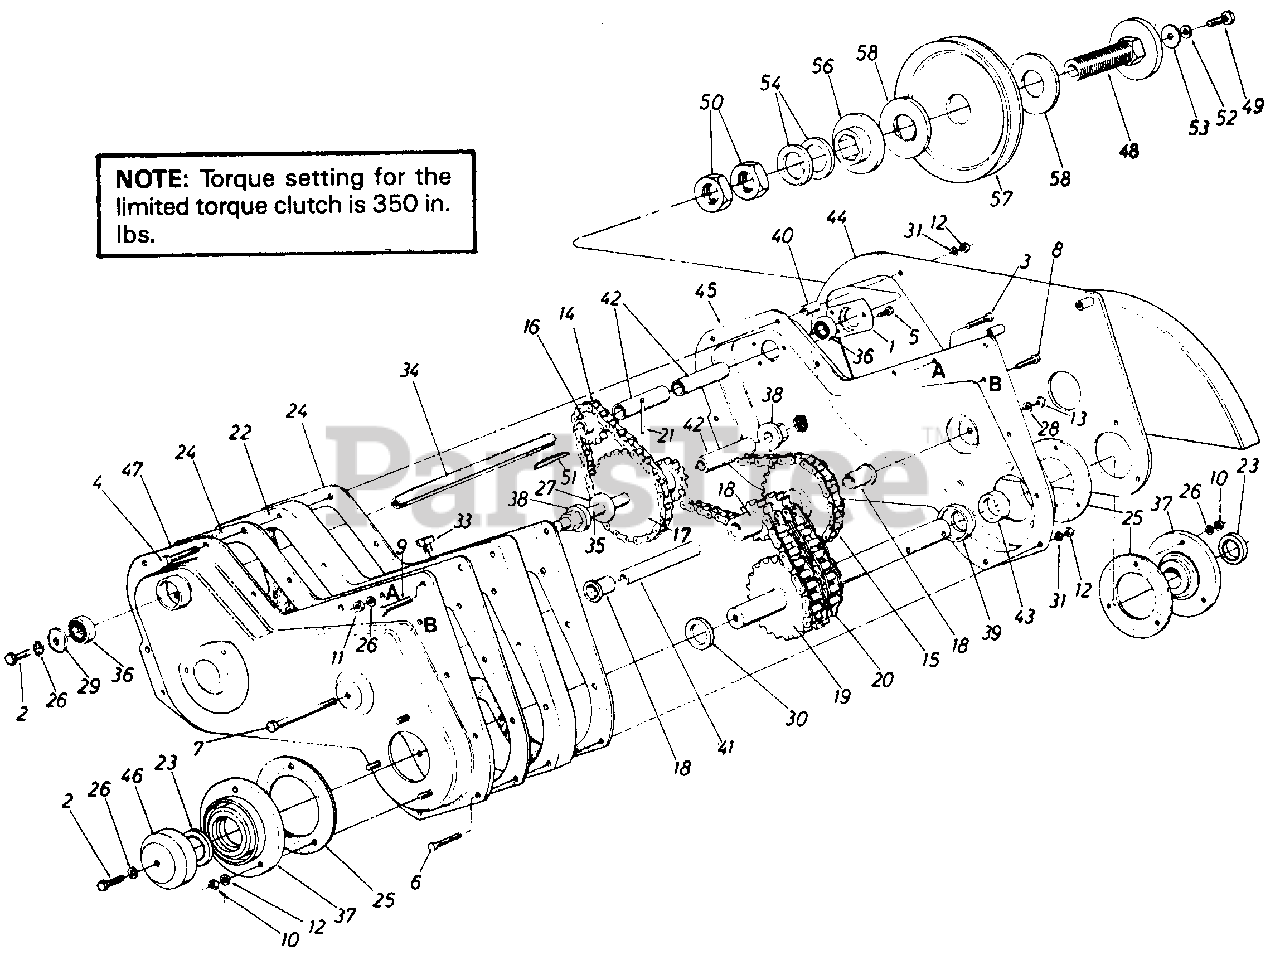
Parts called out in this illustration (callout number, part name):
1	Bearing Housing 1-3/8" Dia.
2	Hex Bolt 5/16-18 x .88" Lg. Spec.
3	Hex Bolt 5/16-18 x 1.50" Lg.*
4	Hex Bolt 1/4-20 x 2.75"
5	Hex Wash. S- Tap. Scr. 1/4-20 x 50" Lg.
6	Hex Bolt 1/4-20 x 1.50" Lg.*
7	Hex Bolt 3/8-16 x 4.5" Lg.
8	Hex Wash. Hd. Bolt 1/4-20 x 1.5" Lg.
9	Hex Wash. TT -Tap Scr. 5/16-18 x 1.75" Lg.
10	Hex Cent. L.-Nut 5/16-18 Thd.
11	Hex Nut 5/16-18 Thd.*
12	Hex Nut 1/4-20 Thd.*
13	Hex Nut 3/8-16 Thd.*
14	#41 Chain 1/2" Pitch x 34 Links - Endless
15	#42 Chain 1/2" Pitch x 48 Links- Endless
16	Sprocket 10 Tooth .500" Pitch
17	10 & 28 Teeth Sprocket Ass'y.
18	8-2 & 28 Sprocket Sleeve Ass'y.
19	18-2 Sprocket Shaft Ass'y.
20	#50-2 Chain 5/8" Pitch x 28 Links- Endless
21	Spring Pin Spir. 1/4" Dia. x 1.50" Lg.
22	Spacer Block - Tiller Housing
23	Oil Seal Double Lip-1-1/4" Dia.
24	Gasket for Tiller Housing
25	Gasket for Brg.-Housing
26	L.-Wash. 5/16" I.D.*
27	Fl.-Wash. .640" I.D. x 1.24" O.D.
28	L.-Wash. 3/8" I.D. Heavy Duty
29	Fl.-Wash. .344" I.D. x 1.125" O.D.
30	Special Washer
31	L.-Wash. 1/4" I.D.*
33	Vent Plug
34	Jack Shaft .525" I.D. x 7.78" Lg.
35	Sprocket Shaft .63" Dia. x 5.0" Lg.
36	Ball Brg. .62" I.D. x 1.38" O.D.
37	Bearing Housing-1-1/4"
38	Hex Flange Brg.
39	Spacel 1.25" I.D. x 2.0" O.D.
40	Spacer .28" I.D. x .62" O.D. x .90" Lg.
41	Spacer.38" I.D. x .62" O.D. x 3.44" 4
42	Spacer .62" I.D. x .88" O.D. x 1.56" Lg.
43	Spacer 1.25" I.D. x 1.62" O.D. x .50 49.
46	Dust Cap .320" Dia. Hole
49	Hex Bolt 5/16-18 x 1.25" Lg. Grade 5
50	Hex Jam Nut 1.0-14 x 28 Thd.
51	Sq. Key 3/16 x 1.50" 4.
52	L.-Wash. 5/16" I.D.*
53	Fl.-Wash. .344" I.D. x 1.125" O.D.
54	Spring Bell Wash. 1.0" I.D. x 2.0" O.D.
56	Floating Disc 3-1/4" O.D. x 1.0" I.D.
57	5/8 V-Pulley 1.50" I.D. x 6.50"
58	Friction Pad 3-1/4" O.D. x 1-3/8" I.D.
